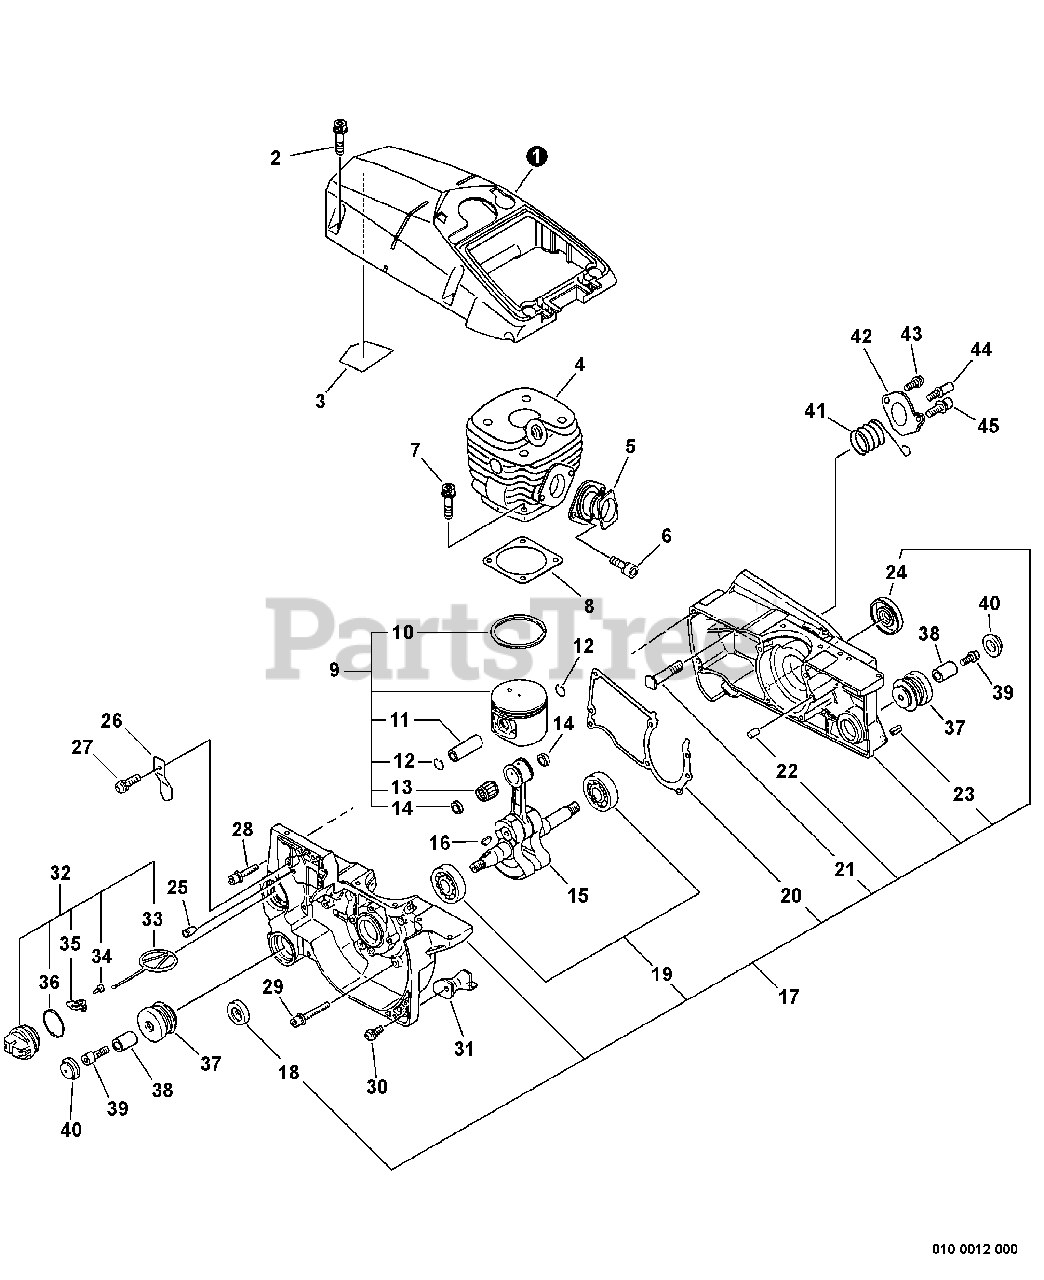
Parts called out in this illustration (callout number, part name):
1	COVER, ENGINE
2	BOLT 5×20
3	SHIELD, HEAT
4	CYLINDER
5	BELLOWS, INTAKE
6	BOLT 5×14
7	BOLT 5×25
8	GASKET, CYLINDER
9	PISTON KIT
10	RING, PISTON
11	PIN, PISTON 12
12	RING, SNAP
13	BEARING, NEEDLE
14	WASHER, THRUST
15	CRANKSHAFT ASSY
16	KEY, WOODRUFF
17	CRANKCASE KIT
18	SEAL, OIL
19	BEARING, BALL 6202
20	GASKET, CRANKCASE
21	STUD, GUIDE BAR 8
22	PIN, LOCATING 5×10
23	PIN, SPRING 5×10
24	SEAL, OIL
25	VENT ASSY
26	PLATE, EYE
27	SCREW 4×8
28	BOLT 5×20
29	BOLT M5×35
30	SCREW 5×14
32	CAP ASSY
33	CONNECTOR, CAP L= 60 MM
34	SCREW, TAPPING 3×8
35	RETAINER, CONNECTOR
37	CUSHION
38	COLLAR 5
39	BOLT 5×25
40	CAP, CUSHION
41	SPRING, COMPRESSION
42	PLATE, EYE
43	BOLT 4×8
45	BOLT 5×14
